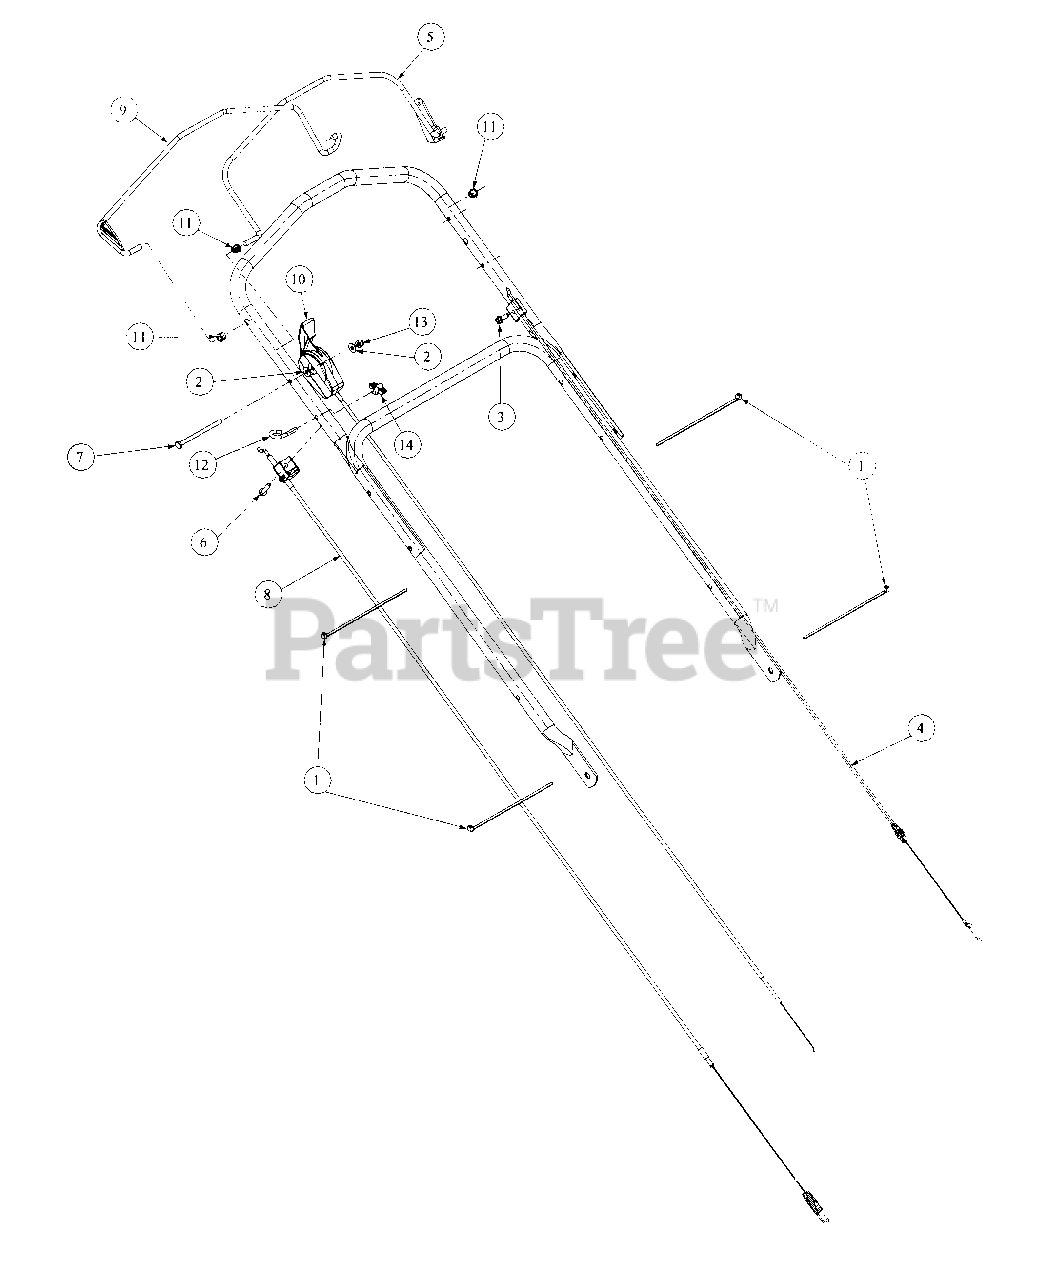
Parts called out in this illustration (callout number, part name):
1	Cable Tie, 3/16 X .05 X 7.4
2	Flatwasher 1/4 X .630 X .0515
3	Screw, TT, 1/4-20, 0.750, Hex Index Washer
4	Control Cable 43" Long
5	Control Lever
6	Screw, TT, 1/4-20, 1.000
7	HHCS, 1/4-20
8	Cable, Clutch Speed Adjuster
9	Clutch Bail, Transmission, Commutator
10	Control Throttle, W/Cable, Briggs
11	Bushing, .3125 Dia Snap
12	Bolt, Eye, 1/4-20, Bent Rope Guide
13	Hex Nut; 1/4-20
14	Handle Knob, 1/4-20
